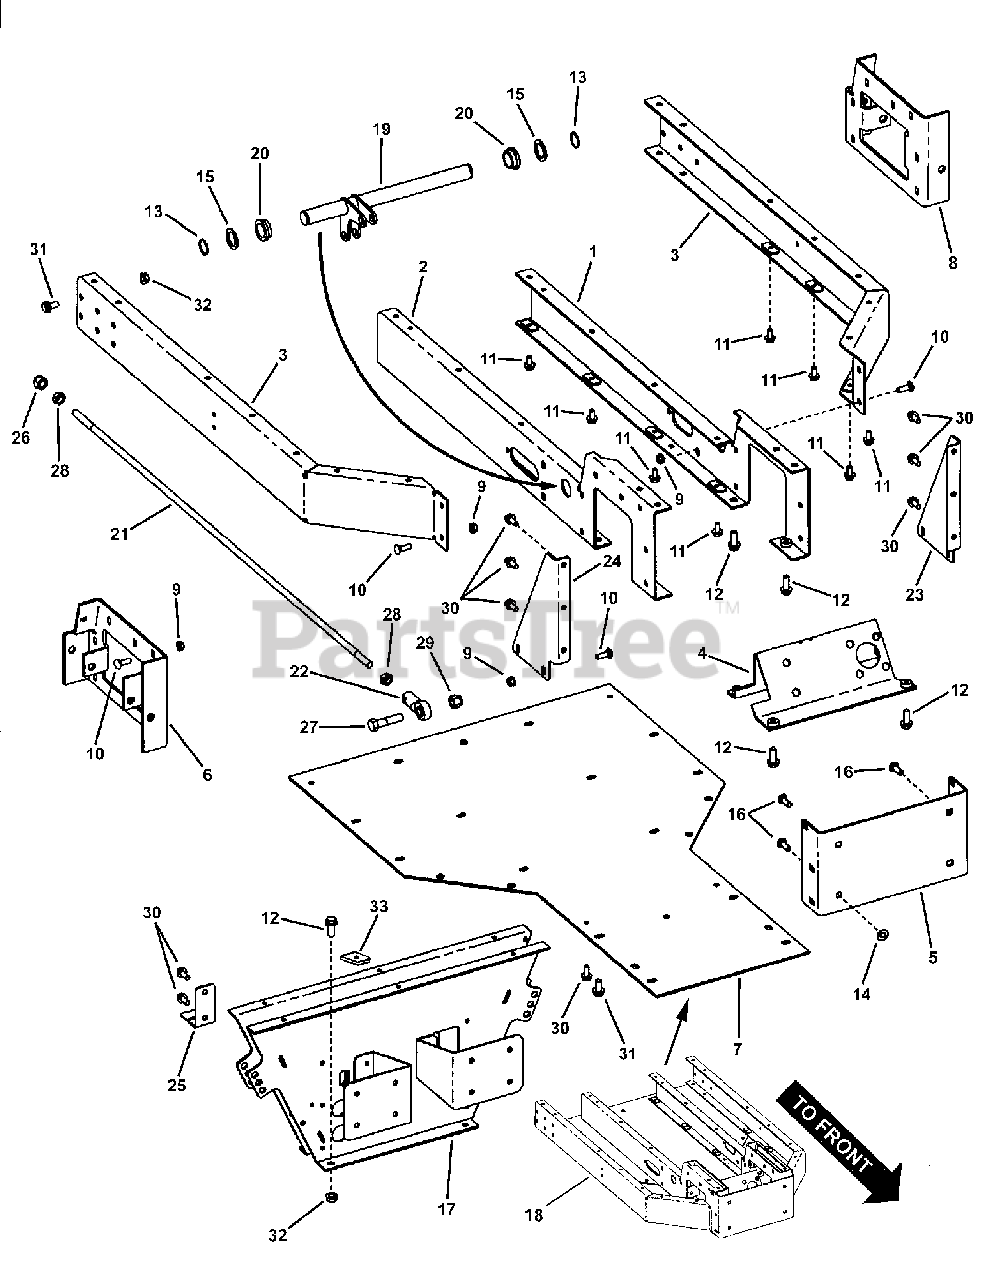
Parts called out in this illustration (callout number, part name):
1	FRAME RAIL ASSEMBLY, Inner LH
2	FRAME RAIL ASSEMBLY, Inner RH
3	FRAME ASSEMBLY, Outer CVT
4	BRACKET ASSEMBLY, Steering
5	END, Frame
6	SUSPENSION PIVOT, RH
7	STIFFENER, Frame
8	SUSPENSION PIVOT, LH
9	NUT, Hex Flange Lock, 5/16-18 GR 5
10	CARRIAGE BOLT, 5/16-18 x 1 GR5
11	BOLT, Hex Flange Lock, 5/16-18 x 5/8 GR 5
12	BOLT, Hex Flange Lock, 3/8-16 x 1 GR 5
13	RING, 1.00 Dia. External Retaining
14	RETAINER, 3/8 Bolt
15	BUSHING, 14 Ga Machine
16	CARRIAGE BOLT, 3/8-16 x 1-1/4 GR 5
17	GRILL SUPPORT
18	FRONT FRAME ASSEMBLY, Assembled (Includes Ref. Nos. 1 thru 12)
19	BRAKE ASSEMBLY, Lower CVT
20	BEARING, 1 I.D.
21	ROD, Lower CVT Brake, 1/2-20 Thread, Both Ends
22	ROD END, Female 1/2-20
23	SUSPENSION GUSSET, LH
24	SUSPENSION GUSSET, RH
25	THROTTLE ANCHOR, Front, Used on Turf Cruiser Models 85632 & 85668
25	THROTTLE ANCHOR, Front, Used on Trail Cruiser Model 85903
26	NUT, Hex Nyloc, 1/2-20
27	CAPSCREW, Hex Head, 1/2-13 x 2-3/4 GR 5
28	NUT, Hex Jam, 1/2-20 GR 5 or B
29	NUT, Hex Nyloc, 1/2-13
30	SCREW, Hex Washer Self-Tap, 5/16-18 x 3/4
31	BOLT, Hex Flange Lock, 3/8-16 x 3/4 GR 5
32	NUT, Hex Flange Lock, 3/8-16
33	NUT, Tinnerman, 1/4
